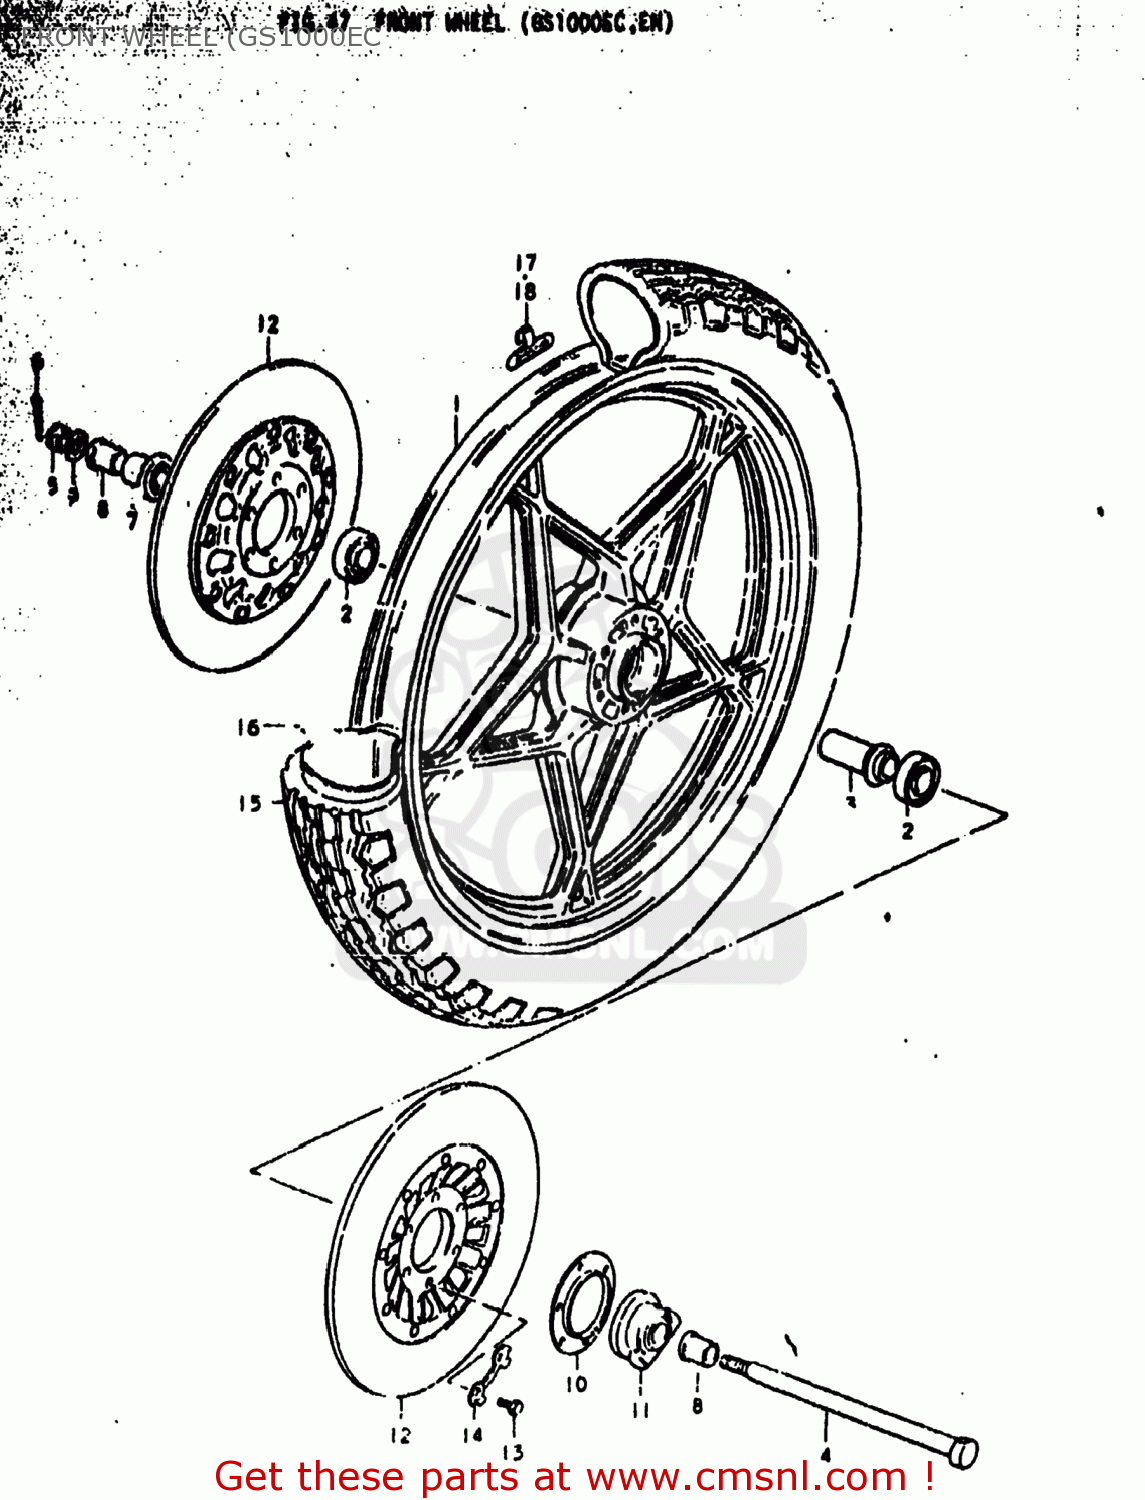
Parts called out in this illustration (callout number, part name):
1	WHEEL, FRONT
2	BEARING
3	SPACER,FR HUB BEARING
4	AXLE,FR
5	NUT 12MM
6	COTTER PIN
7	SPACER,FR AXLE,R
8	SPACER,FR AXLE,L
9	WASHER
10	DUST SEAL
11	BOX ASSEMBLY,SPEEDOMETER GEAR
12	DISC,BRAKE
13	BOLT(8X30)
14	WASHER
15	TIRE,FRONT
16	TUBE,INNER
17	BALANCER,WHEEL
18	BALANCER,WHEEL
